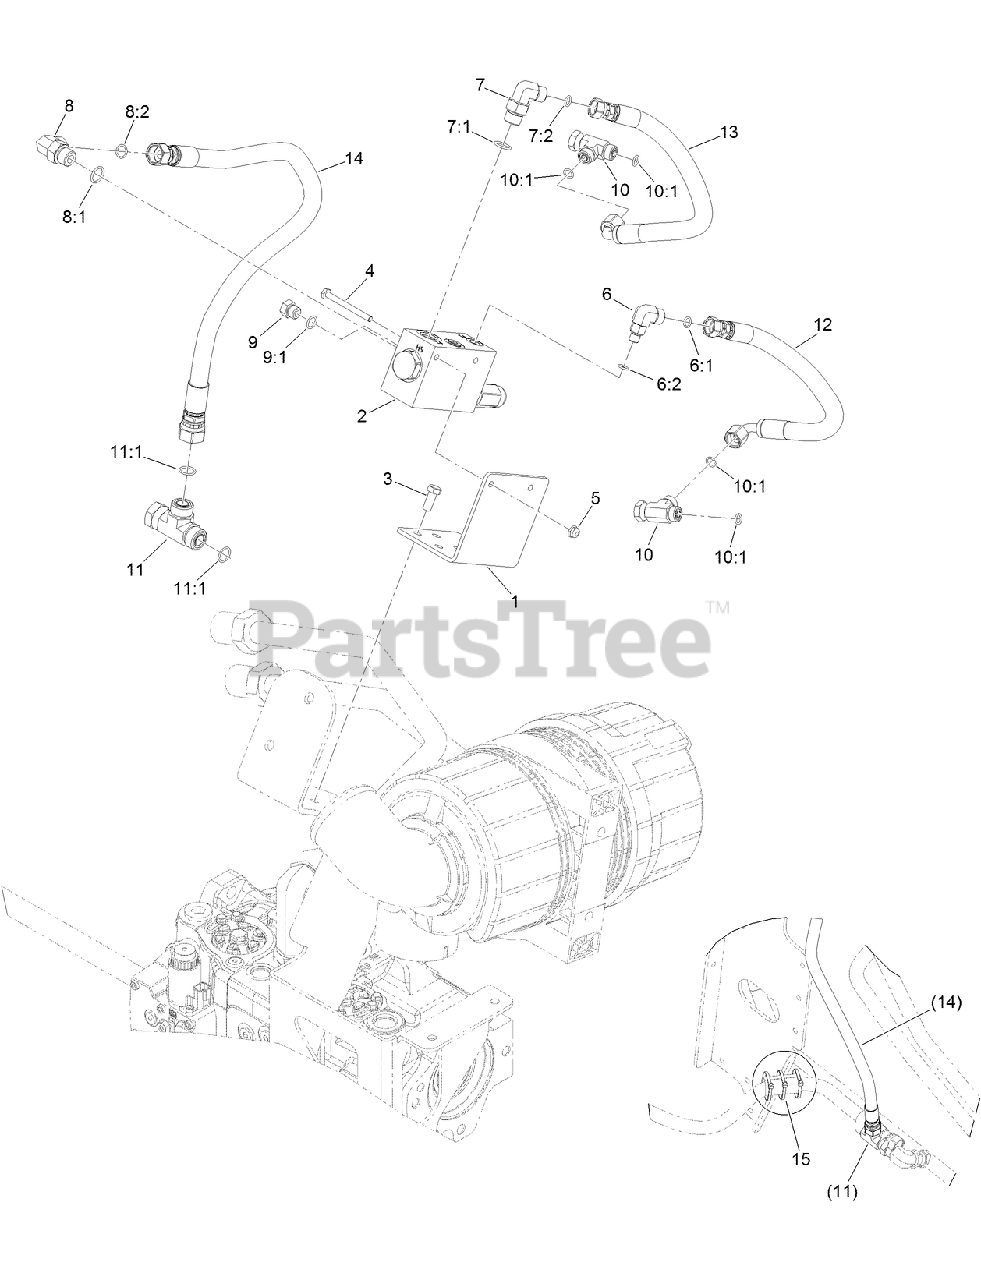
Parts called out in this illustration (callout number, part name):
1	BRACKET-MOUNT, MANIFOLD
2	MANIFOLD-FLUSH
3	SCREW-HH
4	SCREW-HH
5	NUT-HF
6	FITTING-ELBOW, 90 DEG
6:1	O-RING
6:2	O-RING
7	FITTING-HYD, 90 DEG
7:1	O-RING
7:2	O-RING
8	FITTING-ELBOW, 90 DEG
8:1	O-RING
8:2	O-RING
9	PLUG-HH
9:1	O-RING
10	FITTING-TEE, SWIVEL NUT
10:1	O-RING
11	FITTING-HYD, TEE
11:1	O-RING
12	HOSE ASM-HYD
13	HOSE ASM-HYD
14	HOSE ASM-HYD
15	TIE-CABLE
